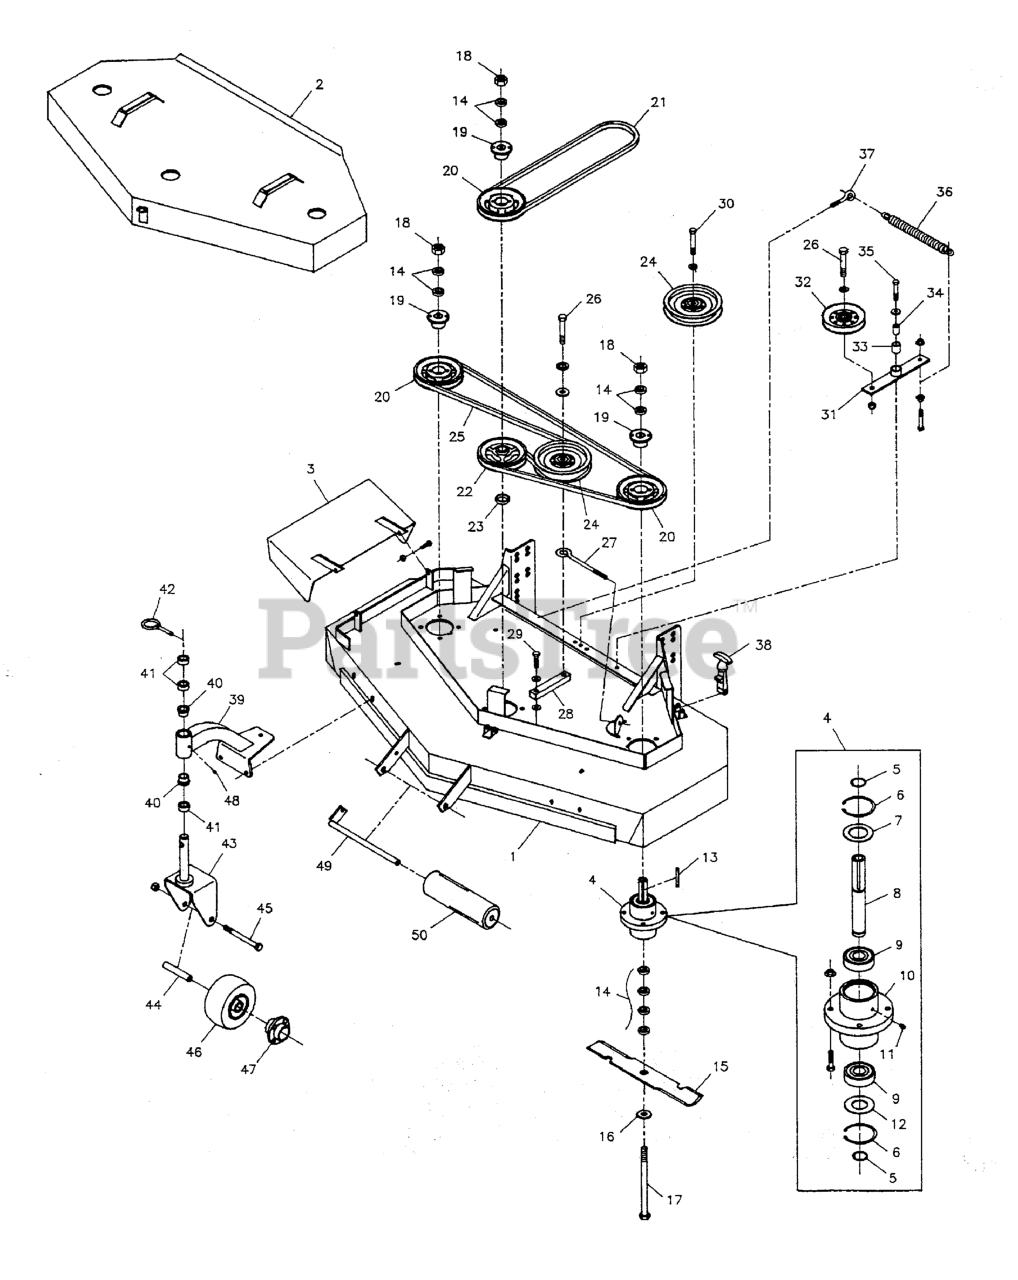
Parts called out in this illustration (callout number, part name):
1	DECK SHELL W/DECALS, 52"
2	52" GUARD
3	CHUTE, DISCHARGE WELDMENT
4	SPINDLE ASSEMBLY, Complete
5	SNAP RING, External
6	SNAP RING, Internal
7	SPINDLE WASHER, Top
8	SPINDLE SHAFT
9	BEARING
10	SPINDLE HOUSING
11	GREASE FITTING
12	SPINDLE WASHER, Bottom
13	KEY, 1/4 SQ. X 2-1/2
14	SPACER, .63 x 1.06 x .23
15	MOWER BLADE, 18"
16	WASHER, 5/8" USS
17	BOLT, 5/8-11 x 9-1/2
18	NUT, 5/8-11 Hex
19	BUSHING, Tapered Hub
20	PULLEY, Spindle
20	PULLEY, Split Steel
21	BELT, Deck Drive
21	Deck Drive Belt
22	SPINDLE PULLEY
22	PULLEY, Split Steel
23	SPACER, 1.00 X 1.25 X .25
24	PULLEY, Backside Idler
25	BELT, Blade Spindle
26	BOLT, 1/2-20 X 2-1/4 GD5 CZ
27	EYEBOLT, 3/8" x 8"
27	J-BOLT
28	ARM, Idler
28	IDLER ARM
29	BOLT, 7/16-20 X 1-3/4" GD.5
30	BOLT, 1/2-20 X 2-1/2" GD5 CZ
31	IDLER ARM, Complete
32	PULLEY, V-Idler
33	BUSHING, Brass
34	SPACER, .32 x .75 x 1.06
35	BOLT, 5/16-18 x 1-3/4
36	SPRING, Extension
37	EYEBOLT
38	RUBBER LATCH
39	CASTER MOUNT, Complete
40	BUSHING, FLANGE
41	SPACER, 1.02 x 1.56 x .50
42	PIN, Lynch
43	YOKE, Caster
44	AXLE, Caster Wheel
45	BOLT, 1/2-13 x 5-1/2
46	WHEEL & TIRE ASSEMBLY, White, 9 x 3.5 x 4, Complete
47	4 BOLT HUB W/ BEARING
48	GREASE FITTING
50	ROLLER
